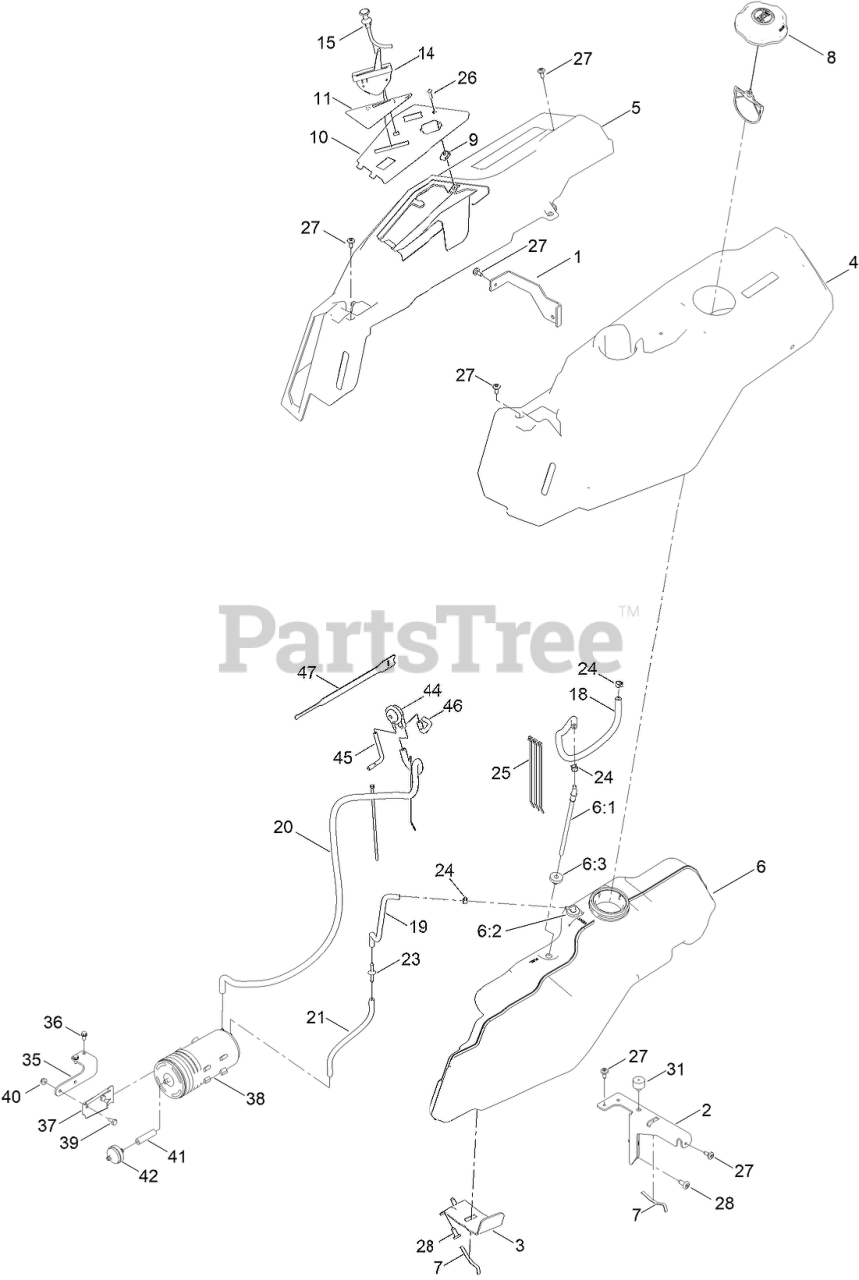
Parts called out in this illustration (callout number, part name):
1	BRACKET-POD
2	SUPPORT-POD, LH
3	SUPPORT-TANK, FUEL
4	POD-LH
5	POD-RH, MYRIDE
6	TANK-FUEL ASM
6:1	CONNECTOR-ELBOW, 90 DEG
6:2	FITTING-ELBOW 90
6:3	BUSHING
7	SPRING
8	CAP-FUEL, RATCHETING
10	PANEL - CONTROL
11	DECAL-PANEL, CONTROL
14	CABLE-THROTTLE
15	CABLE-CHOKE
18	HOSE-FUEL
19	HOSE-FUEL
20	HOSE-FUEL
21	HOSE-FUEL
23	ADAPTER ORIFICE
24	CLAMP-HOSE
25	TIE-CABLE
26	SCREW-PRH
27	SCREW-SHOULDER
31	BUMPER-GROMMET
35	BRACKET-CANISTER, CARBON
36	SCREW-HWH
37	BRACKET-CANISTER, CARBON
38	CANISTER-CARBON, 800CC
39	SCREW-HH
40	NUT-HF
41	HOSE-FUEL
42	FILTER-FUEL, INLINE
44	VALVE-CONTROL, VACUUM
45	HOSE-VENT, FORMED
46	HOSE-VENT, FORMED
47	STRAP-VELCRO, CABLE TIE
